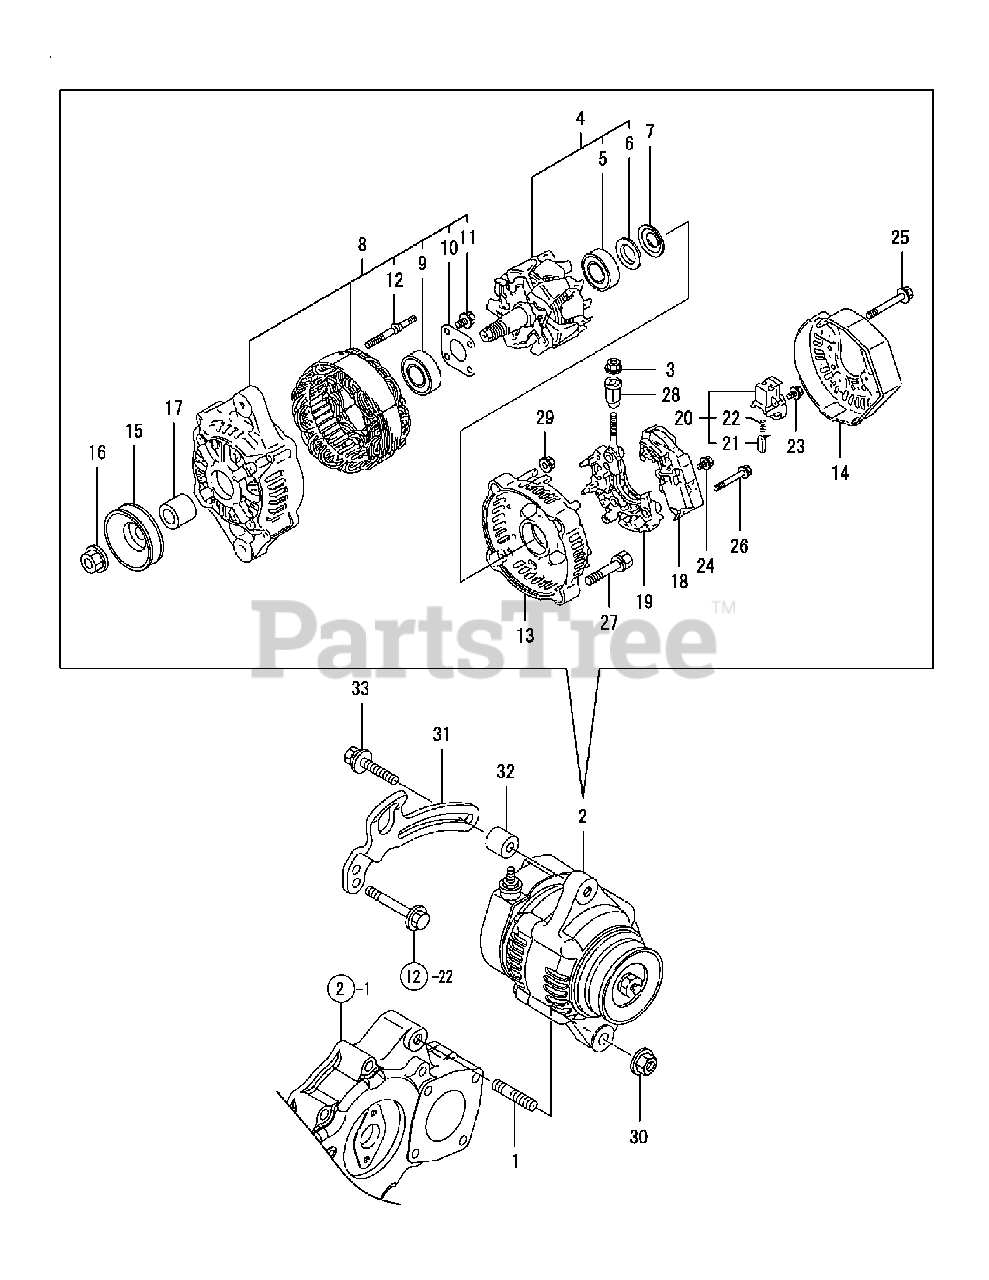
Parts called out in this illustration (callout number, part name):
2	GENERATOR, 40A
6	COVER, BEARING
7	WASHER, THRUST
8	FLAME ASSY, DRIVE
10	PLATE, RETAINER
13	FLAME ASSY, REAR
14	COVER, REAR END
18	REGULATOR ASSY
28	BUSH, INSULATION
31	ADJUSTER, BELT
33	BOLT, ADJUSTER
